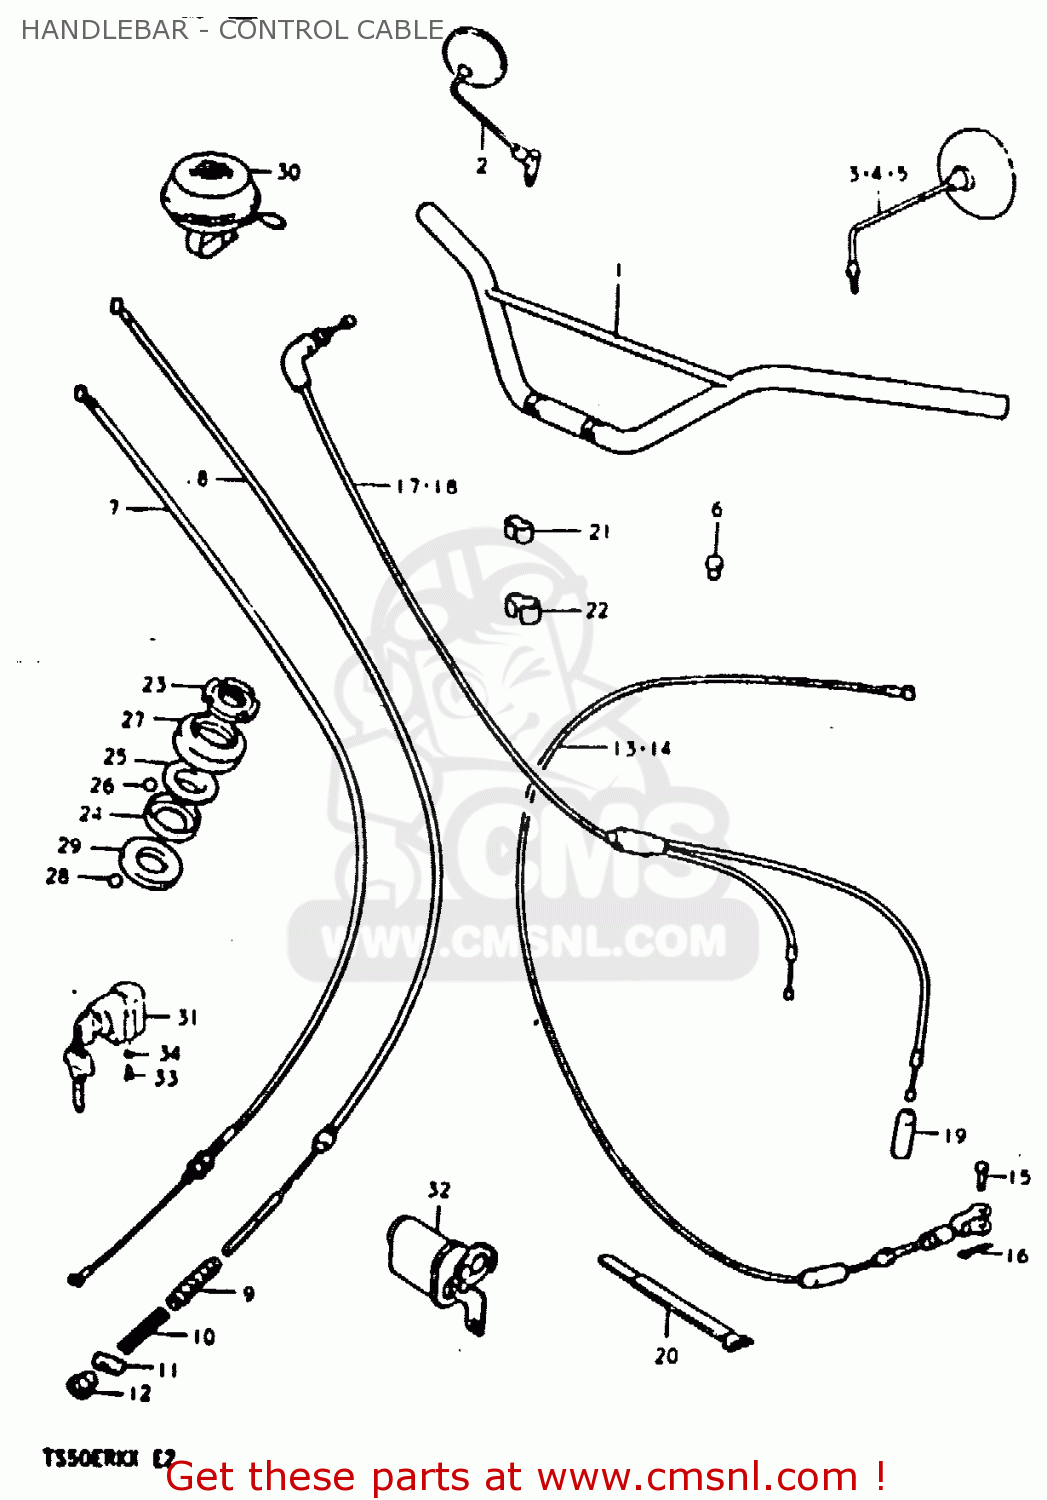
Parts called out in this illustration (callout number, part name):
1	HANDLEBAR
2	MIRROR ASSY, REAR VIEW
6	CAP
7	CABLE ASSY, BRAKE
13	CABLE ASSY,CLUTCH
15	PIN(L:13)
16	PIN
17	CABLE ASSY, THROTTLE
19	SEAL,DUST(7X18X30)
20	CLAMP
23	NUT,STEERING STEM(25X44X10)
24	RACE,STEERING INNER UPR
25	RACE,STEERING OUTER UPR
26	BALL
27	DUST SEAL,STEERING UPR
28	BALL
29	LACE,STEERING INNER LWR
31	LOCK ASSEMBLY,STEERING
33	SCREW
34	LOCK WASHER
